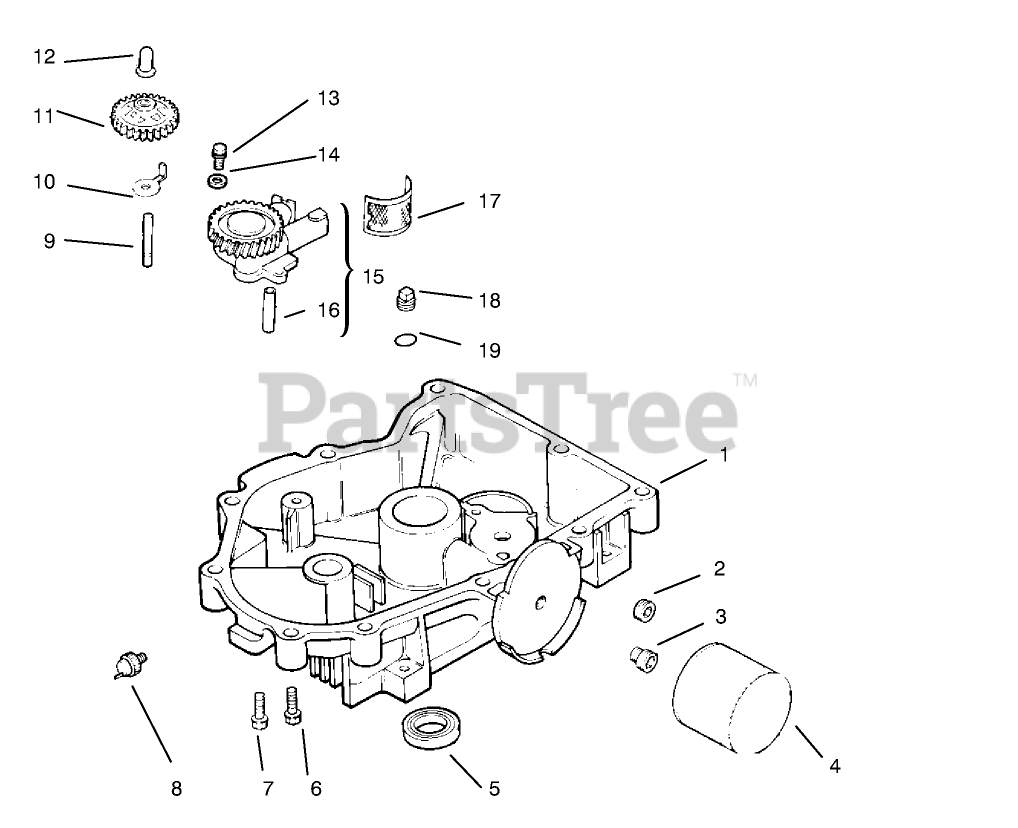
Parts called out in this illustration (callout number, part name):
1	Oil Pan
2	Plug-HS 3/8 NPTF (Only On: 72103, 72083)
3	Nipple-Oil Filter
4	Filter-Oil
5	Seal-Oil
6	Screw M8x1.25x45 (Only On: 72103, 72083)
8	Switch-Oil Pressure
9	Shaft-Govenor Gear
10	Tab-Locking
11	Kit-Governor Gear Assembly (Incl. Ref. #7)
12	Pin-Governor
15	Oil Pump ASM INC 16
16	Tube-Oil Pickup (Only On: 72103, 72083)
17	Screen-Oil Pickup
